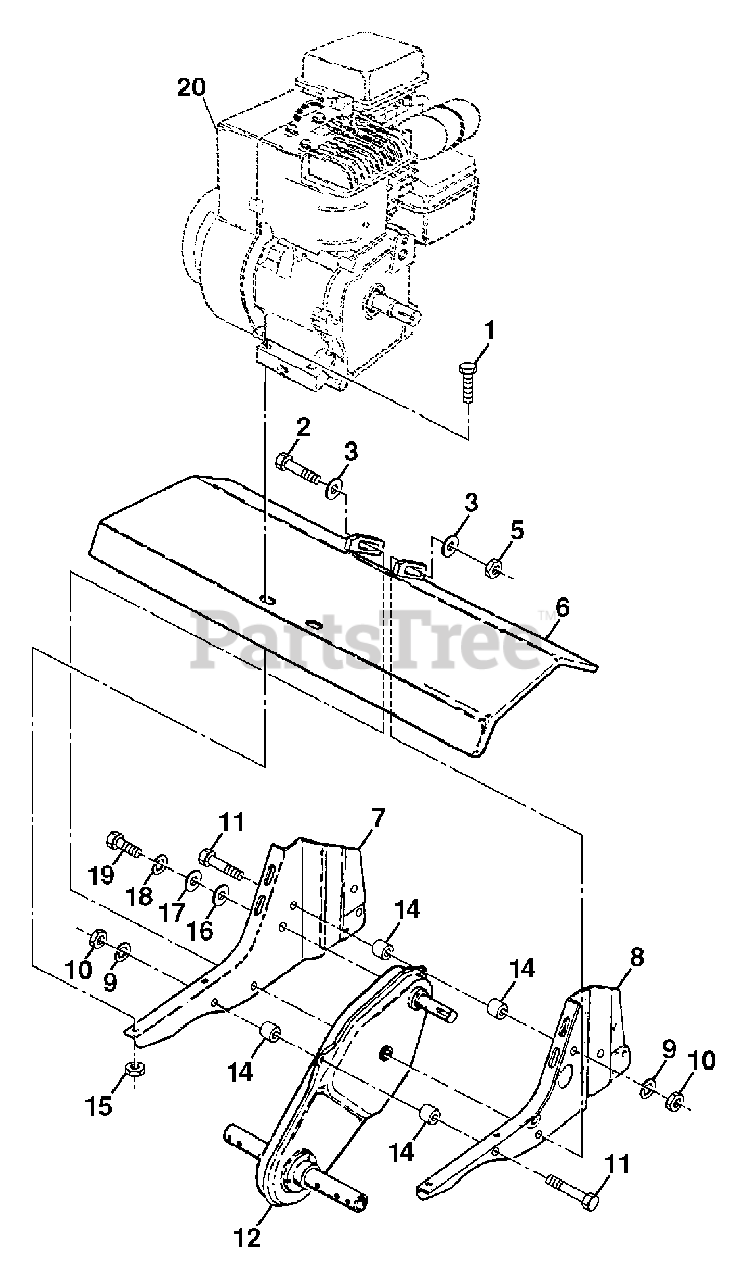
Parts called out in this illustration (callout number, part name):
1	Bolt, Hex 5/16-18 x 1-1/2 Gr. 2
2	Bolt, Hex, Fin 3/8-16 x 3-1/4
3	Washer 13/32 x 13/16 x 11
5	Locknut, Hex, w/washer 3/8-16
7	Bracket, Engine, R.H.
8	Bracket, Engine, L.H.
9	Washer, Lock 5/16
10	Nut, Hex 5/16-18
11	Bolt, Hex 5/16-18 x 2-3/4
12	Transmission
14	Spacer, Split
15	Nut, Keps 5/16
16	Washer 9/32 x 7/8 x 12 Ga.
17	Washer 9/32 x 1-1/4 x 16 Ga.
18	Washer, Lock 1/4
19	Bolt, Hex 1/4-28 x 3/4 Gr. 5
